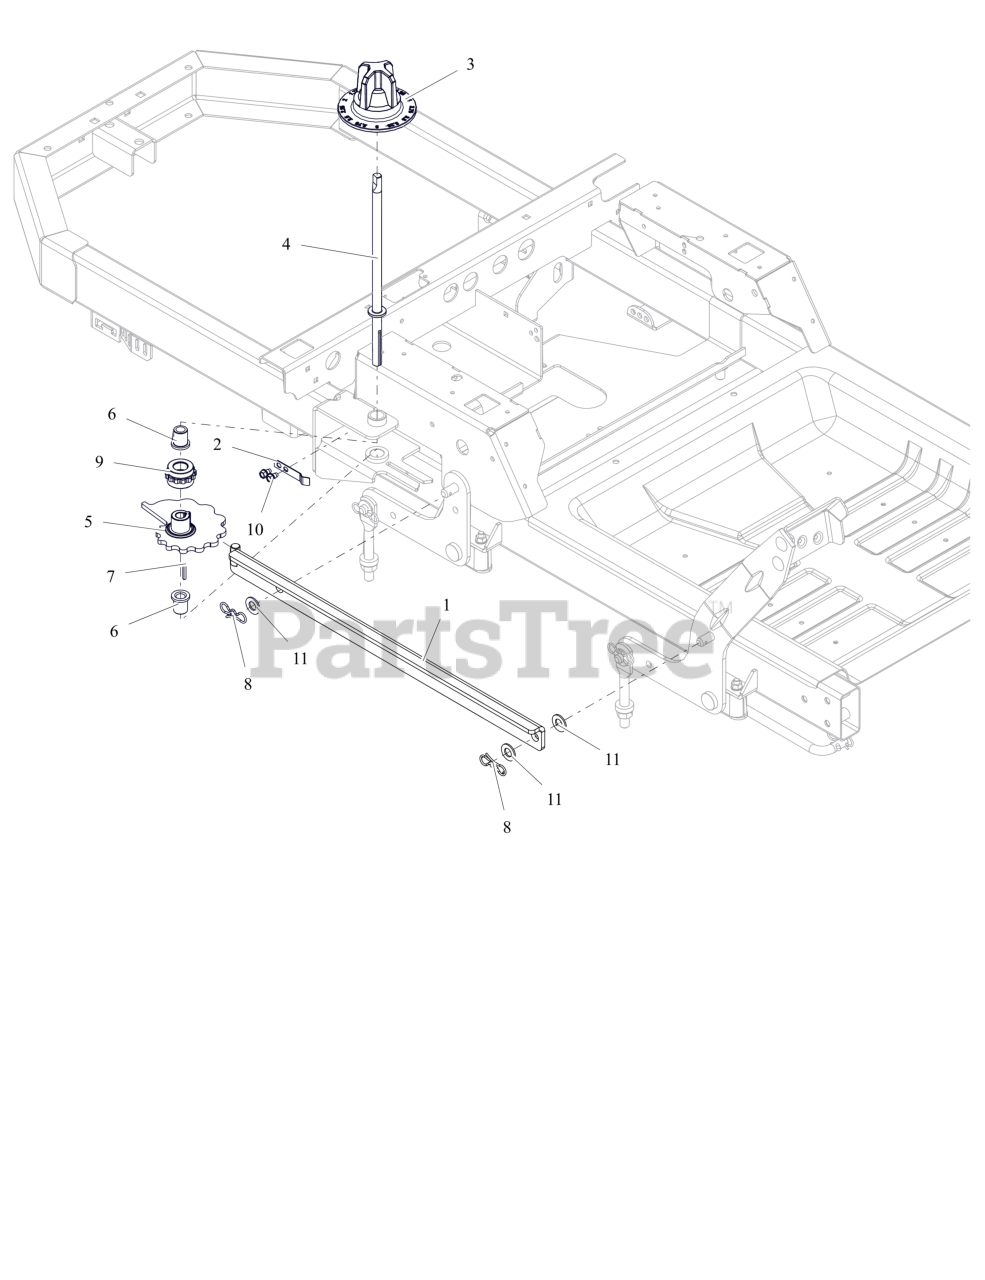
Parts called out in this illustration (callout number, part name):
1	WLDMT, HOC LINK
2	ARM, HOC DETENT
3	KNOB, HOC DIAL
4	SHAFT, CAM
5	CAM, HOC (PM)
6	BSHG-FLG, .503X.750X.875X1.00
7	KEY, 1/8 X 1/8 X 1.0
8	PIN, BOWTIE .091X1.875 ZCC
9	GEAR, HOC INDEX
10	SCR,TAP .25-20X.375 HWH TR ZCC
11	WSHR-FL-NYL .518X1.000X.080
